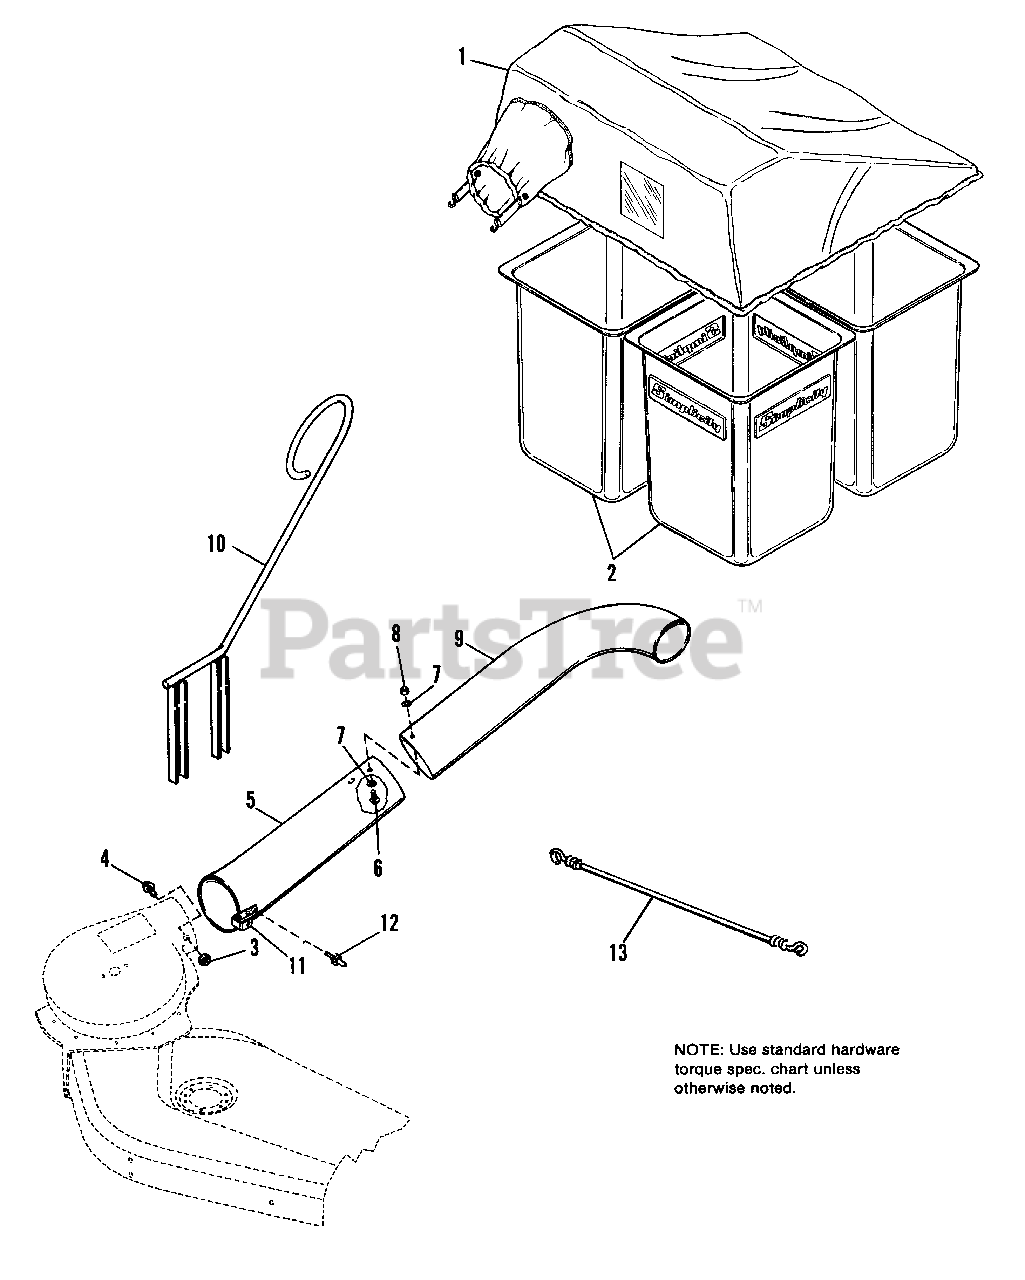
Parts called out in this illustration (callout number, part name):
2	BASKET, Grass Collector (Mfg. No. 1691870 Only)
2	BASKET, Grass Collector (Mfg. No. 1692031 Only)
3	NUT, Hex, Flange, Lock, 1/4-20
4	CARRIAGE BOLT, 1/4-20 x 5/8
5	TUBE ASSY., Lower (Incl. Ref. Nos. 11 & 12)
6	SCREW, Truss Hd., #10-32 x 1/2
7	WASHER, Plain, #10
8	NUT, Hex, Washer Assy., #10-32
9	TUBE, Upper
10	SUPPORT, Tube
11	CLIP, Spring
